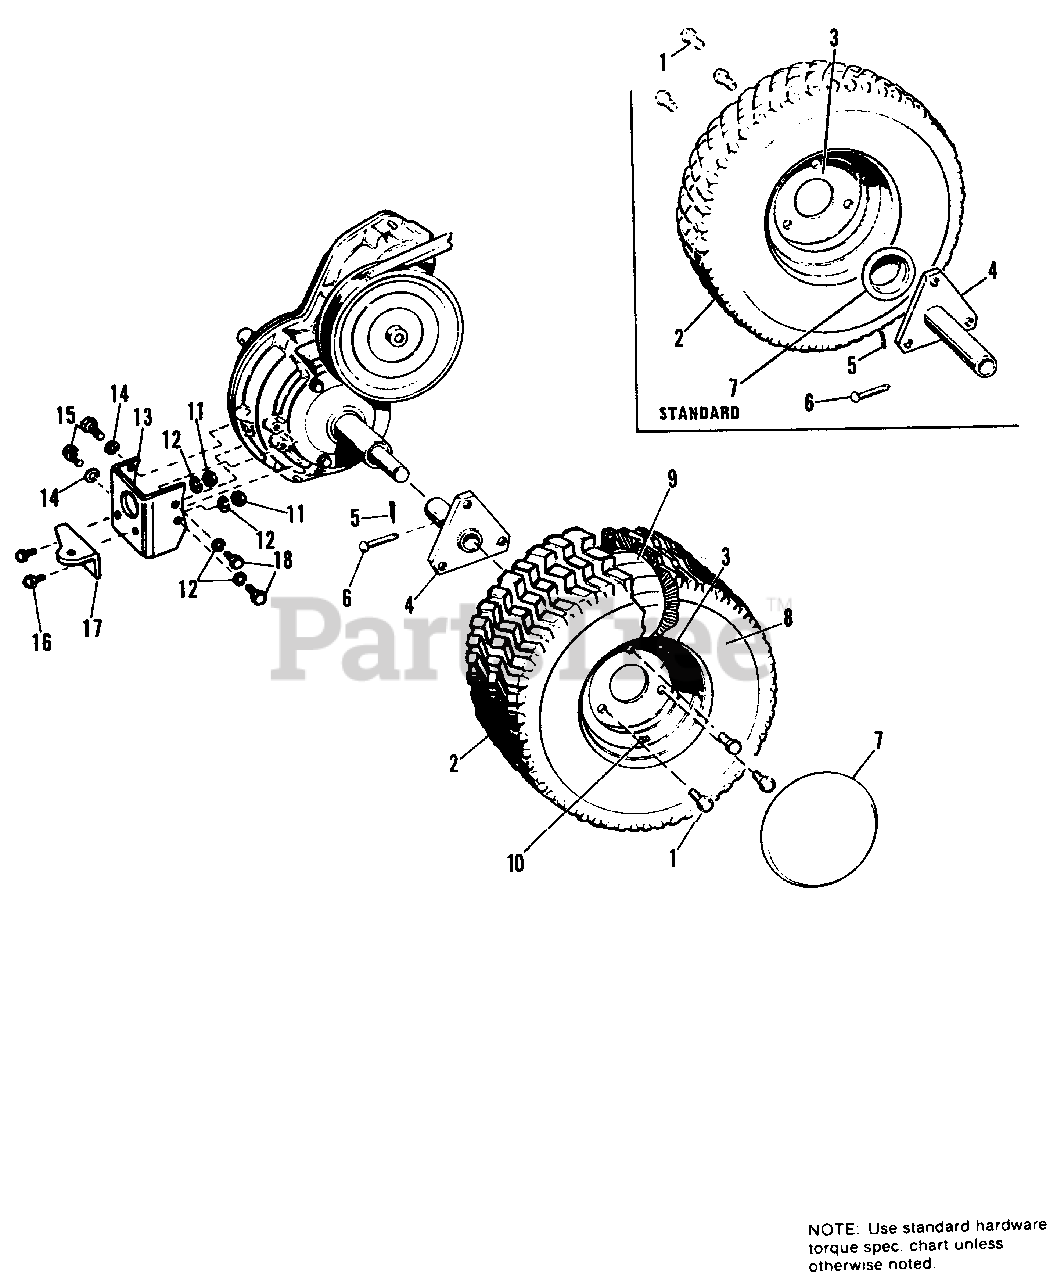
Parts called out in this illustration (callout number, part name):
2	WHEEL & TIRE ASSY., Std. (990287 & 990373 0nly)
2	WHEEL & TIRE ASSY., Deluxe
3	WHEEL (990287 & 990373 Only)
4	HUB ASSY., Wheel, Std. (990287 & 990373 Only)
4	HUB ASSY., Wheel, Deluxe
5	PIN, Cotter, 1/8 x 3/4
6	PIN
7	HUB, Cap, Rear, Std. (990287 & 990373 Only)
7	HUB CAP, Rear, Deluxe
8	TIRE, Deluxe (990288, 990303, 990374, 990375, 990424, 990425 & 990489 Only)
9	TUBE (For Service Only)
10	VALVE STEM & CAP
11	NUT, Hex, Full, 3/8-16
12	LOCKWASHER, 3/8
13	BRACKET, Draw Bar
14	LOCKWASHER, 5/16
15	CAPSCREW, Hex Hd., 5/16-18 x 1-1/4
16	CAPSCREW, Hex Hd., 3/8-16 x 1
17	CLIP, Draw Bar Hitch
18	CAPSCREW, Hex Hd., 3/8-16 x 3/4
